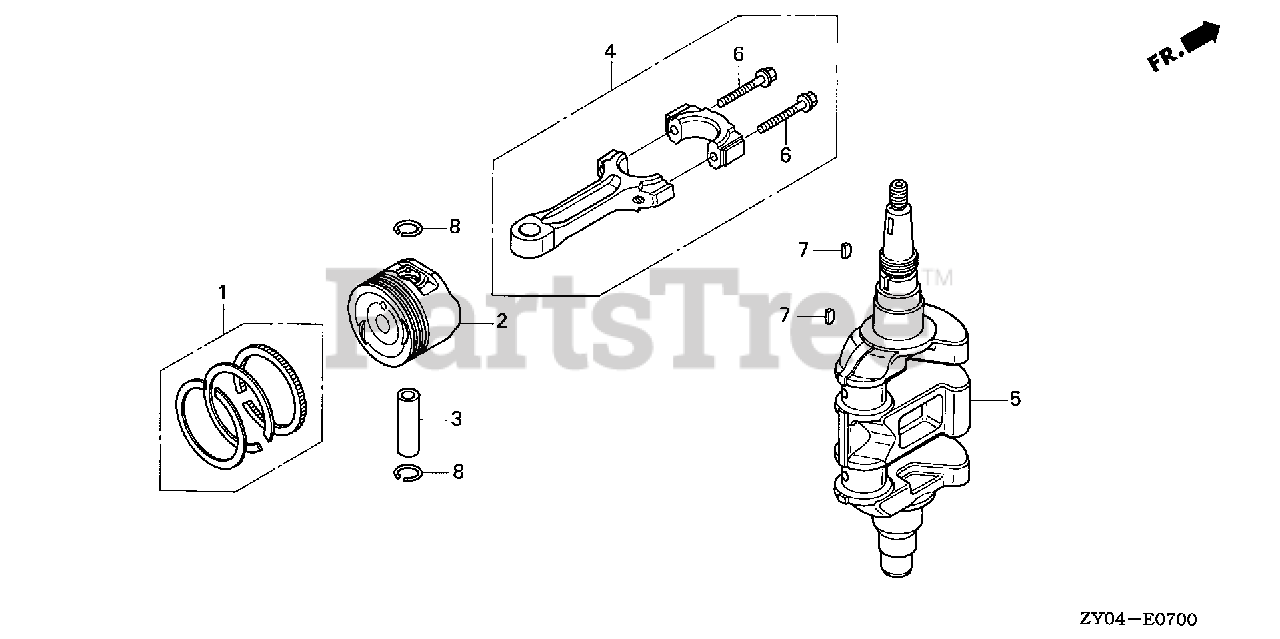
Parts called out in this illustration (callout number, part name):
1	RING SET, PISTON
3	PIN, PISTON
4	ROD, CONNECTING
5	CRANKSHAFT
6	BOLT, CONNECTING ROD (6X34)
7	KEY, SPECIAL (16X13)
8	CLIP, PISTON PIN (16MM)
